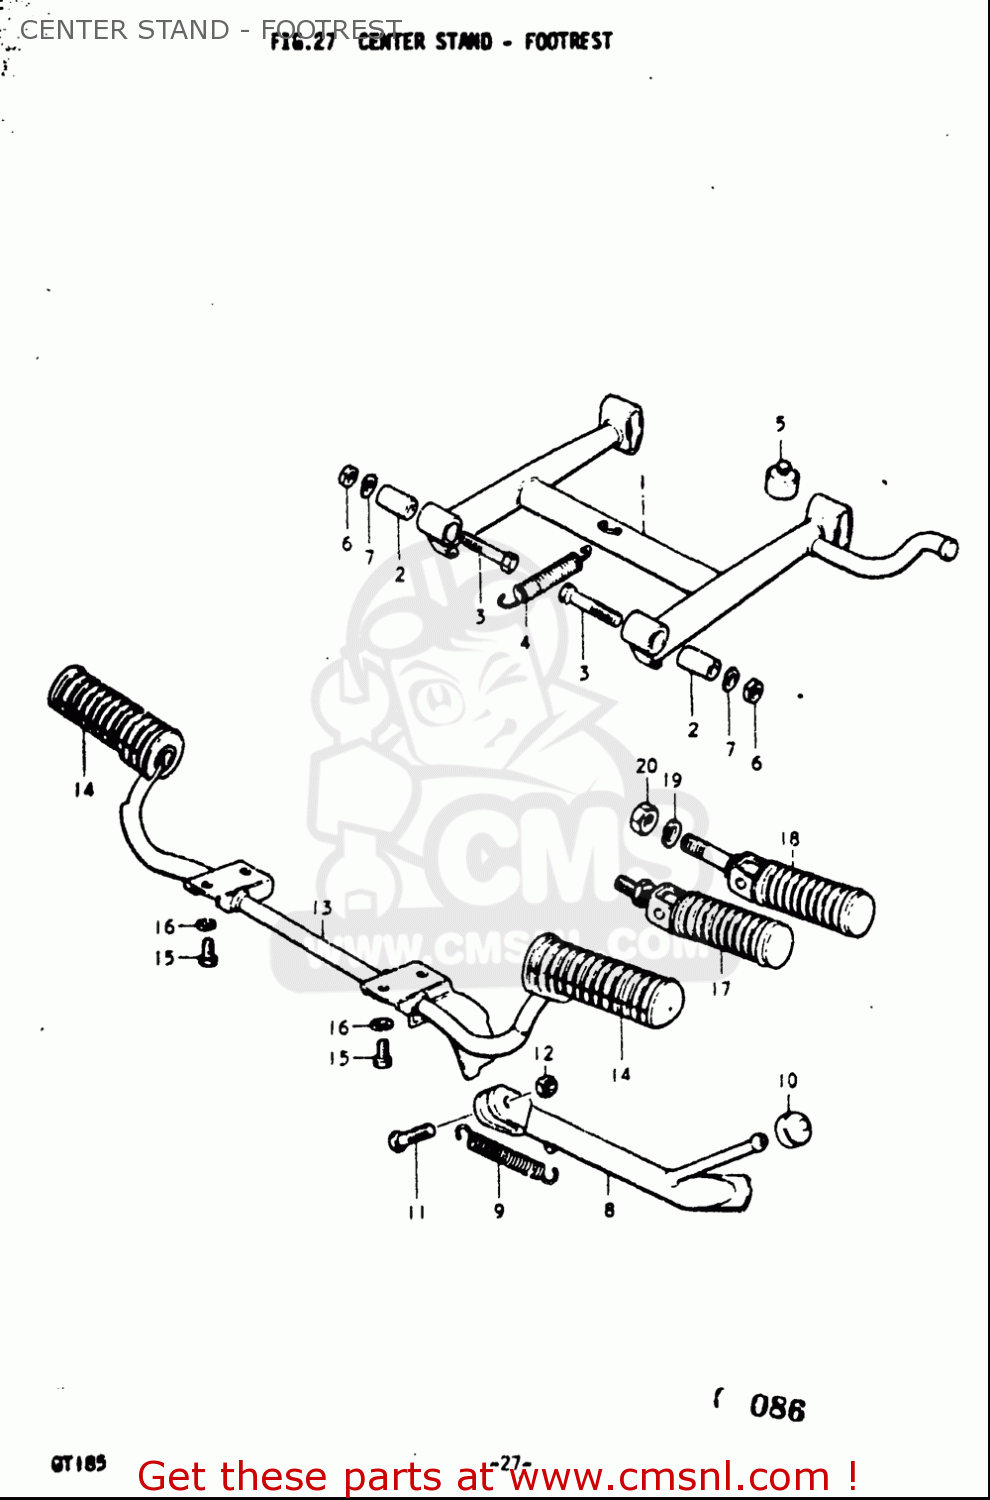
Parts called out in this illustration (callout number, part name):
2	SPACER(10.5X16X30)
3	BOLT(10X48)
4	SPRING
5	CUSHION
6	NUT
7	WASHER,LOCK
9	SPRING
10	CUSHION
11	BOLT(10X27)
12	NUT
14	RUBBER,FR FOOTREST
15	BOLT
16	WASHER,LOCK
17	FOOTREST ASSEMBLY,PILLION
18	FOOTREST ASSY,PILLION
19	WASHER,LOCK
20	NUT
